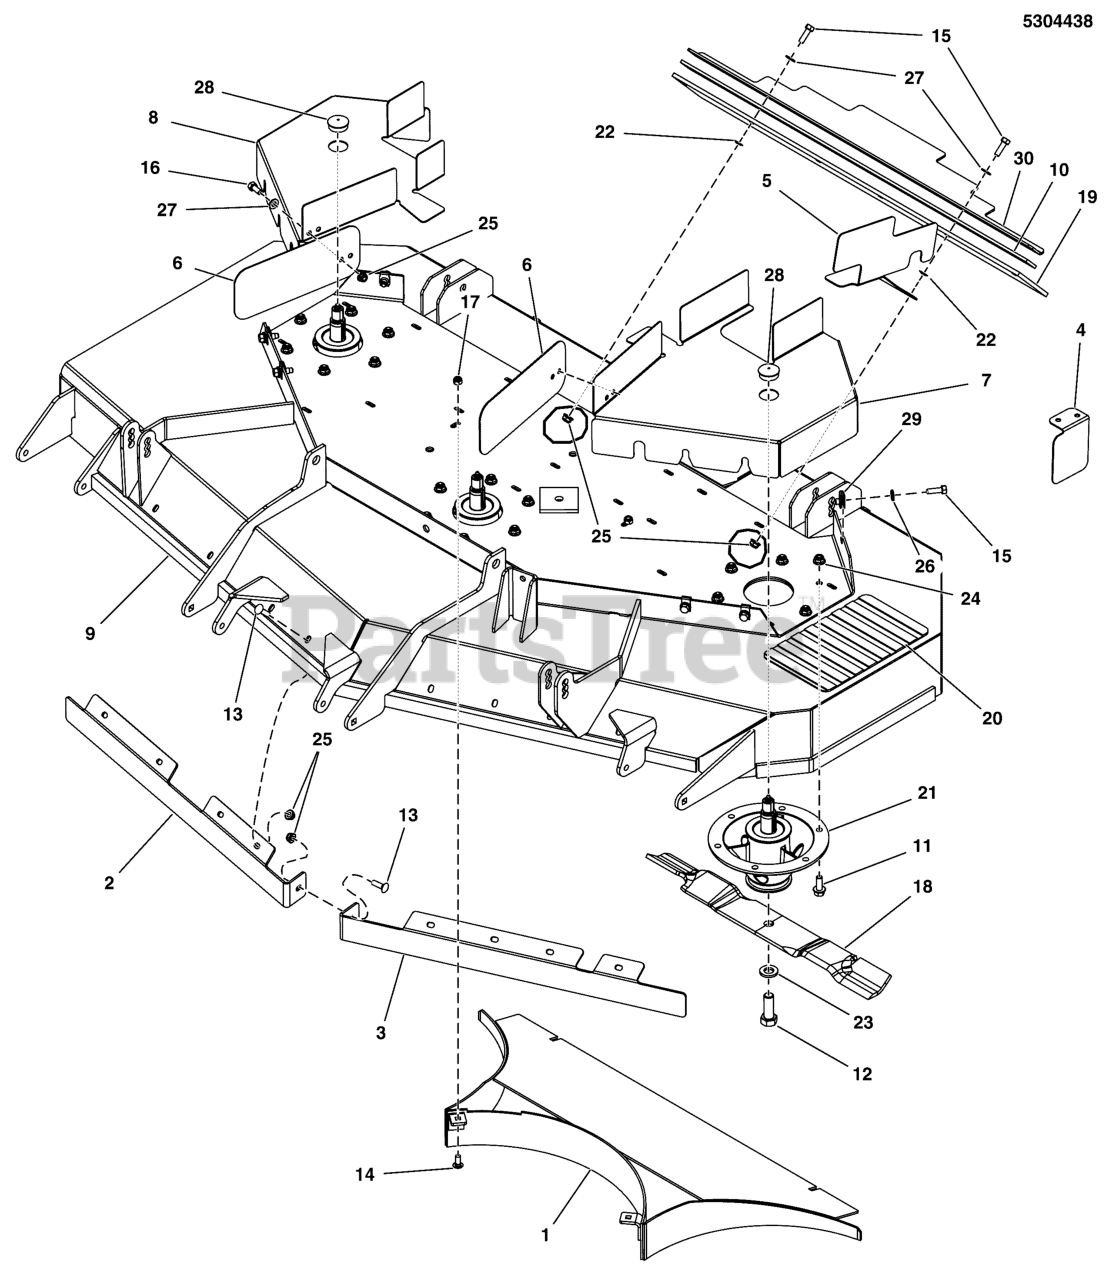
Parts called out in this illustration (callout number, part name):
1	WELD, REAR BAFFLE, 61RD, SHRT - BLK
2	BAFFLE, BLOWOUT, 61 ICD, RH - RED
3	BAFFLE, BLOWOUT, 61 ICD, LH - RED
4	PLATE,DECK BELT GUARD,REAR,LH,61 CE -RED
5	PLATE, DECK BELT GUARD,LH REAR,IS2600 EU
6	PLATE, GUARD, DECK - IS2600Z EU - RED
7	PLATE, GUARD, LH DECK - IS2600Z EU - RED
8	PLATE, GUARD, RH DECK - IS2600Z EU - RED
9	DECK SHELL W/DECALS,61RDCE,2600,5413819B
9	DECK SHELL W/DECALS, 2600-61E (5417039B)
10	PLATE, SUPPORT - BLKV
11	BOLT, 3/8-16 X 1, FLANGE, GD 5, CZ
12	BOLT, 5/8-11 X 1-3/4 GD8
13	BOLT, 5/16-18 X 1, CARRIAGE, GD5, CZ
14	BOLT, 5/16-18 X 3/4, CARRIAGE, GD5, CZ
15	BOLT, 5/16-18 X 1" GRD5 YZ
16	BOLT, 5/16-18 X 3/4 GD5
17	NUT, 5/16-1/8, HEX, CNTR LK, ZINC PHOS/OIL
18	BLADE, SET, MULCH, 61 DECK
19	FLAP, STRIPER, 61" DECK, IS3100, S200X
20	SAFETY WALK, 9.75 X 6.00
21	SPINDLE ASSM, CAST IRON 8.0 - 6-BOLT
22	5/16" PUSH-ON NUT RETAINER, STL, CZ
23	WASHER, BLADE BOLT, 9/16" F436, CZ
24	NUT, 3/8 - 16 HEX NYLOCK FLANGE
25	NUT, 5/16-18 HEX NYLOCK FLANGE NUT
26	WASHER, 5/16 GRADE 9, FLAT
27	WASHER, 5/16" SAE
28	PLUG, PANEL, 1.25 - BLACK
29	BODY CLIP, 5/16-18-7GA MATERIAL
30	PLATE, REAR DEFLECTOR, 61RD - BLK
